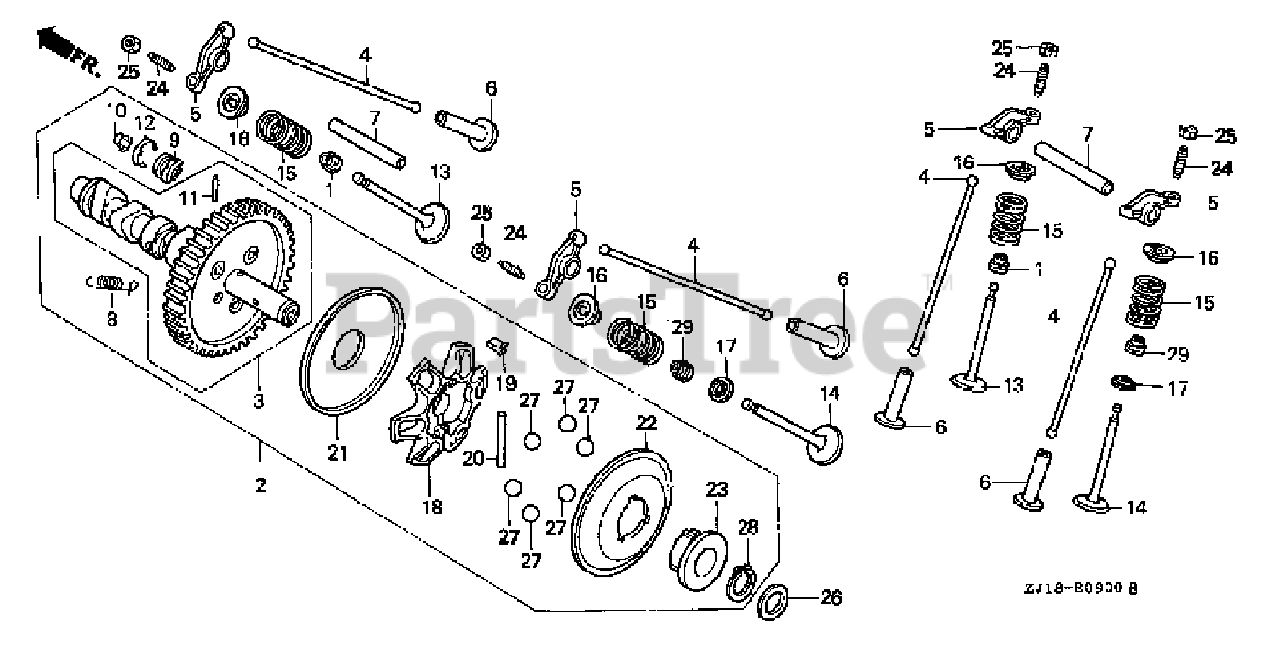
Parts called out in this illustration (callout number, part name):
1	SEAL, VALVE STEM
2	CAMSHAFT ASSY.
3	CAMSHAFT
4	ROD, PUSH
5	ARM, VALVE ROCKER
6	LIFTER, VALVE
7	SHAFT, ROCKER ARM
8	SPRING, WEIGHT RETURN
9	HOLDER, DECOMPRESSION PIN
10	PIN A, DECOMPRESSION
10	PIN B, DECOMPRESSION
10	PIN C, DECOMPRESSION
10	PIN D, DECOMPRESSION
10	PIN E, DECOMPRESSION
11	ROD, DECOMPRESSION
12	SPRING, DECOMPRESSION PIN HOLDER
13	VALVE, IN.
14	VALVE, EX. (STELITE)
15	SPRING, VALVE
16	RETAINER, IN. VALVE SPRING
17	SEAT, VALVE SPRING
18	HOLDER, GOVERNOR WEIGHT
19	PLATE, GOVERNER WEIGHT HOLDER
20	PIN, GOVERNOR WEIGHT HOLDER
21	PLATE, GOVERNOR (LOWER)
22	PLATE, GOVERNOR SLIDER
23	SLIDER, GOVERNOR
24	SCREW, TAPPET ADJ.
25	NUT, TAPPET ADJ.
26	WASHER, THRUST (17.2MM)
27	BALL, STEEL (18)
28	CIRCLIP (OUTER) (17MM)
